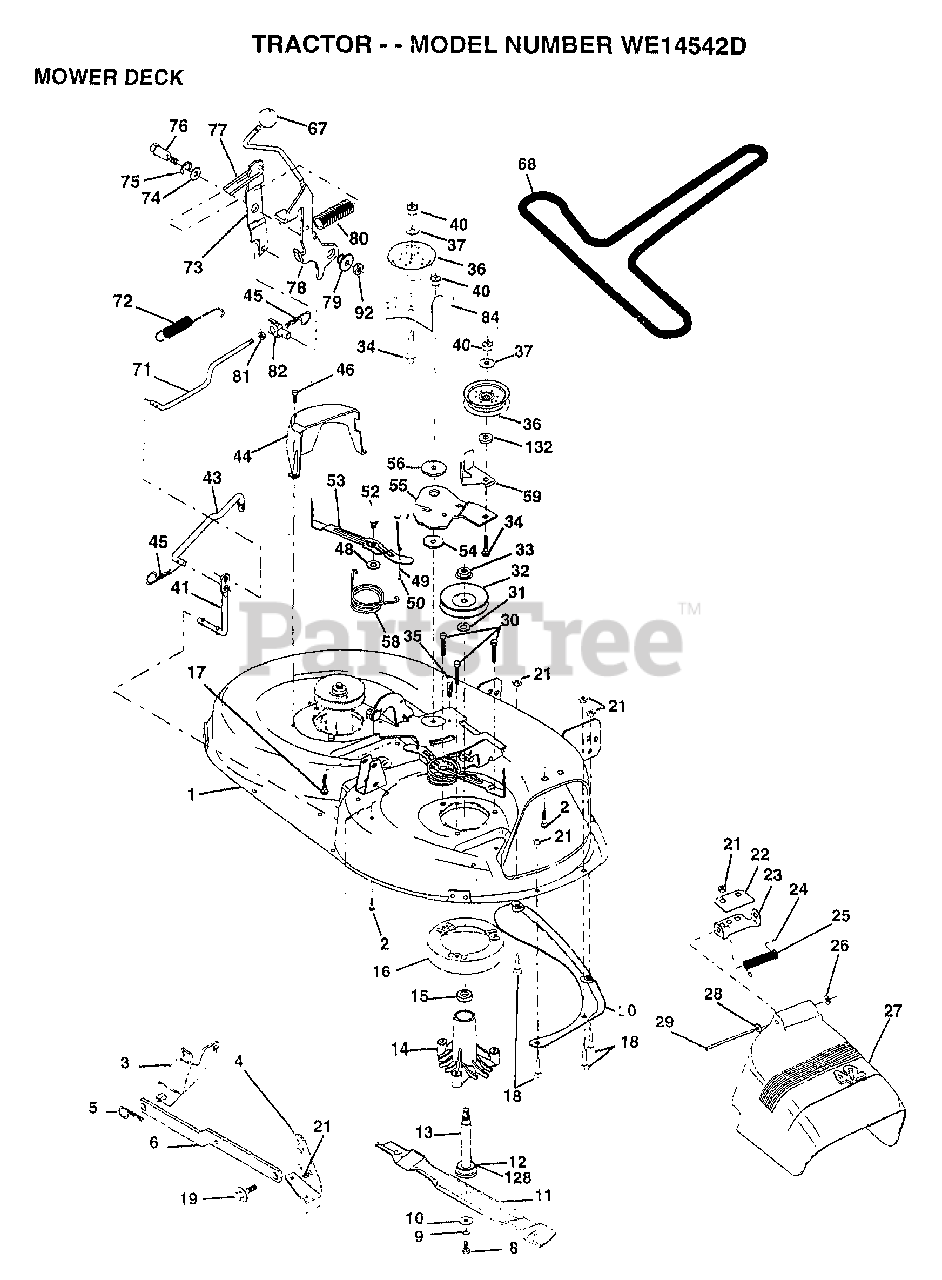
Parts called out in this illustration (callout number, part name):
1	DECK.WELD.42.
2	BOLT
3	BRKT ASM SWAY BAR
4	BRKT DECK SW BAR
8	BLADE BOLT
10	WASHER.HARD.BLADE
11	"BLADE.42"" HIPERF"
12	BEARING.BALL
14	HSG ASM MANDREL
15	BEARING
16	STRIPPER RND MWR
17	BOLT RDHD 3/8-16
18	BOLT
19	BOLT SHD 5/16-18
22	STIFFENER BRKT
23	DEFLECTOR BRKT
24	CAP-SLEEVE LT
25	SPRING TORSION
26	NUT PUSH M
27	DEFLECTOR.SHIELD
28	WASHER
29	HINGE ROD
31	WASHER
32	PULLEY.MANDREL.42
34	BOLT
35	XMAS TREE FASTNER
36	FLAT IDLER PULLEY
37	WASHER
41	PIVOT ROD
43	ROD CLUTCH W/NIBS
44	GUARD MAND LH BLK
45	RETAINER M
46	SCREW.1/4-20X5/8
48	HARD SMALL WASHER
49	ROLLER ASM-CAM
50	SHOULDER BOLT
51	LOCKNUT
52	BOLT.SHLD.5/16-18
54	HARDENED WASHER
55	ARM-IDLER
56	SPACER RETAINER
58	SPRING TORSN BRAK
59	GUARD IDLER TUV
67	KNOB T(3/8 HOLE)
68	BELT-V.SEC.46.KEL
71	ROD CLUTCH 38/42
72	RETURN SPRING
73	CLUTCH ARM SECOND
74	WASHER
75	RING
76	SHOULDER BOLT
77	SPRING KEEPER
78	LEVER ASM-CLUTCH
79	BUSHING
80	SPRING.CLUTCH.MWR
81	TRUNION ADJ
82	NUT
84	BRACKET ASM IDLER
92	NUT
128	WASHER.FELT.
132	WASHER GT
